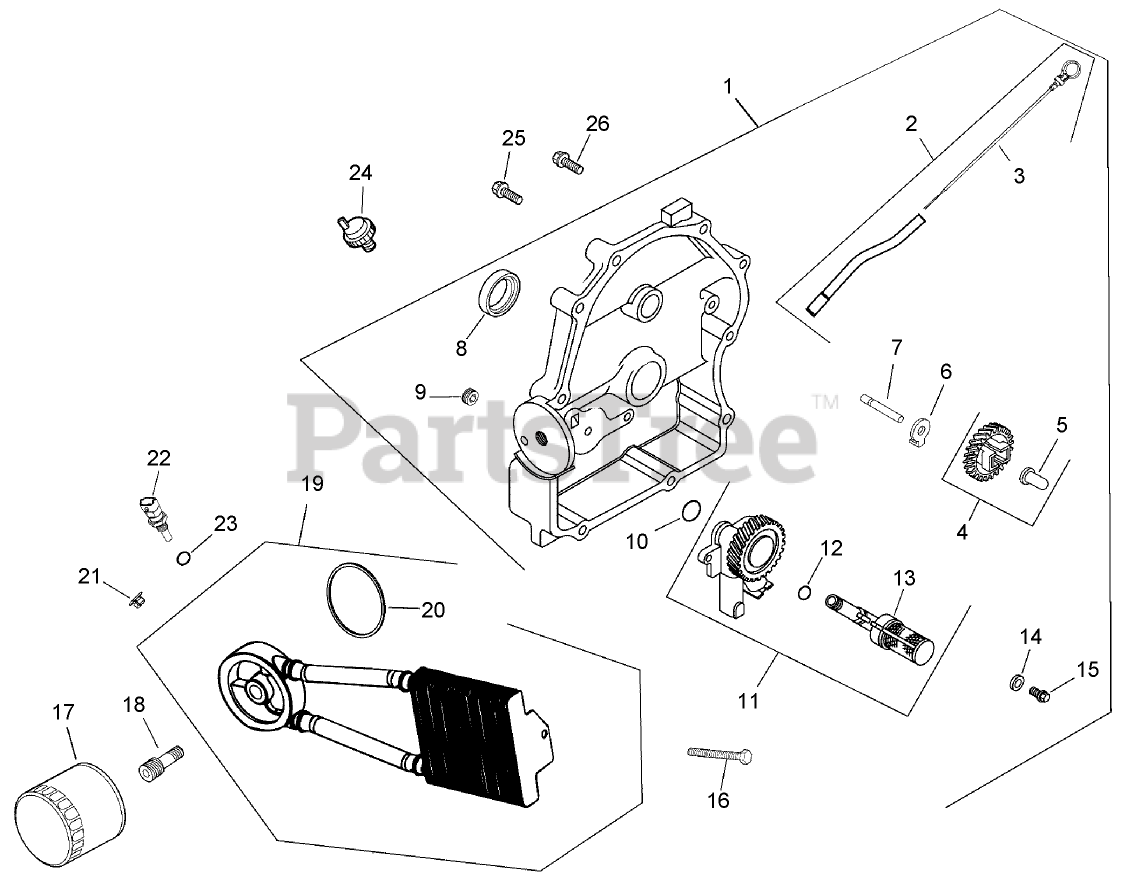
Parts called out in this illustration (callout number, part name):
1	Closure Plate Kit (Includes 2-15)
2	Dipstick Tube ASM (Includes 3)
3	Dipstick
4	Governor Gear Kit (Includes 5)
5	PIN-REGULATING, GOVERNOR
6	TAB-LOCKING
7	SHAFT-GEAR, GOVERNOR
8	Seal-Oil (PTO end)
9	PLUG-PIPE, COUNTERSUNK (1/8)
10	O-Ring
11	Oil Pump ASM (Includes 12, 13)
12	O-RING
13	TUBE-PICK UP, OIL
14	WASHER-FLAT (6 MM)
15	SCREW-FLANGE, THREAD FORMING (M6X1.0X25)
16	SCREW-TAPPING
17	FILTER-OIL
18	NIPPLE-FILTER, OIL
19	Cooler-Oil (Includes 20)
20	O-RING
21	Nut-Plastic
22	Sensor-Temperature
23	O Ring-Oil Pick-up
24	SWITCH-PRESSURE, OIL
25	Screw-HF (M8x1.25x45)
26	SCREW-FLANGE (M8X1.25X45)
